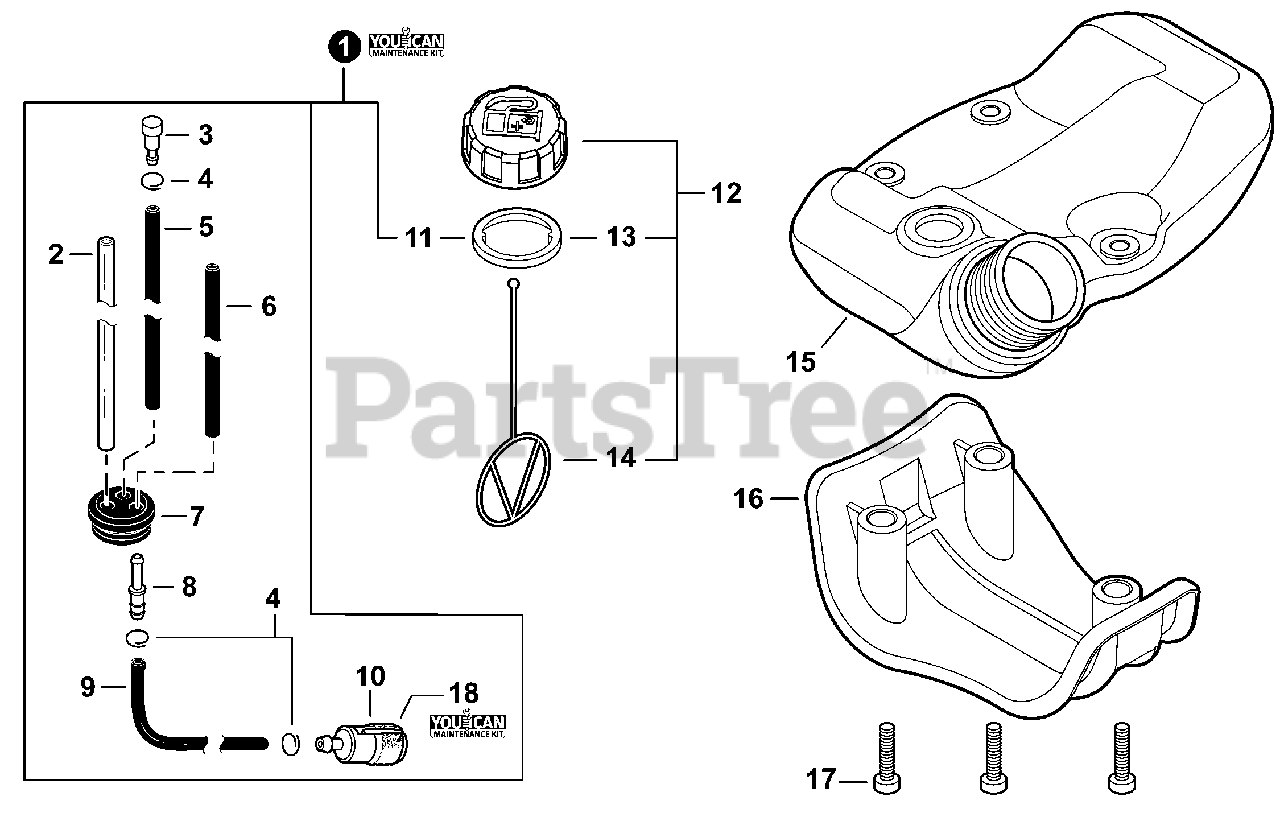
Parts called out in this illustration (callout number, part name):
1	FUEL SYSTEM KIT - YOUCANT
2	PIPE, FUEL 3×6×80 CLEAR
3	VENT ASSY
4	CLIP Ø6
5	PIPE, FUEL 3×5×90 BLACK
6	PIPE, FUEL 3×5×74 BLACK
7	GROMMET, FUEL Ø5
8	CONNECTOR, PIPE Ø5ר3.5
9	PIPE, FUEL 3×5×110 BLACK
10	FILTER, FUEL
11	GASKET, FUEL CAP
12	CAP ASSY, FUEL
13	GASKET, FUEL CAP
14	CONNECTOR, CAP L= 123
15	TANK ASSY, FUEL
16	GUARD, FUEL TANK
17	BOLT, TORX 5×25
18	TUNE-UP KIT - YOUCANT
